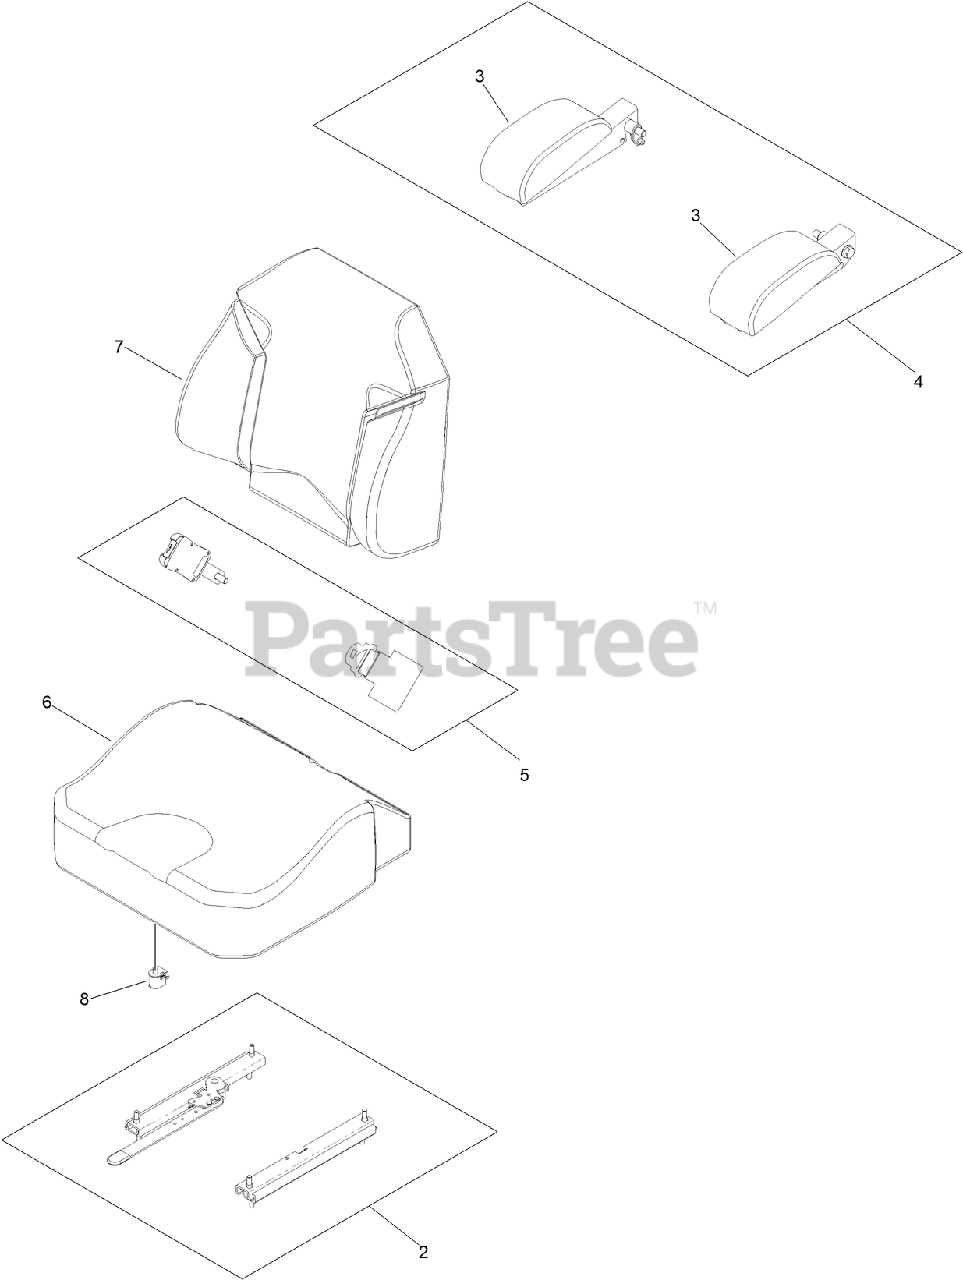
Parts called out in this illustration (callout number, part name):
2	SEAT TRACK SET
3	ARM REST PAD SET
4	ARM REST SET
5	SEAT BELT KIT
6	COVER-CUSHION
7	COVER-BACK
8	SWITCH-BAIL
